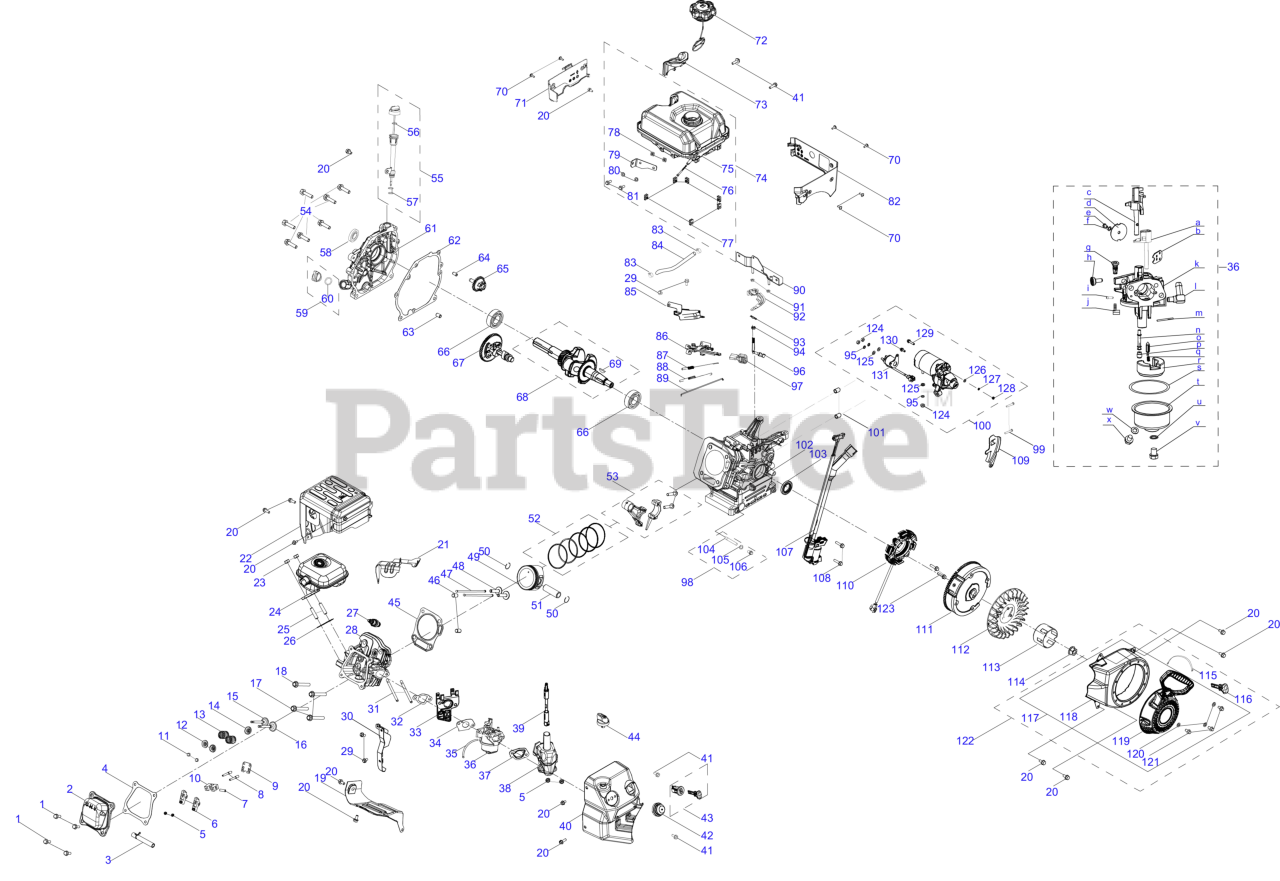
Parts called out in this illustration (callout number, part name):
1	BOLT M6 x 16
2	VALVE COVER
3	BREATHER HOSE
4	VALVE COVER GASKET
5	HEX NUT
6	ROCKER ARM ASSEMBLY
7	ROCKER ARM SHAFT
8	PIVOT BOLT
9	PUSH ROD GUIDE
10	ROCKER ARM PIVOT BLOCK
11	EXHAUST VALVE ADJUSTER
12	EXHAUST VALVE SPRING RETAINER
13	VALVE SPRING
14	INTAKE VALVE SEAL
15	EXHAUST VALVE
16	INTAKE VALVE
17	SCREW M10-1.25 x 65 x GR10.9
18	BOLT M10-1.25 x 70
19	AIR SHIELD
20	BOLT M6-1 x 12 GR8.8
21	SHROUD
22	MUFFLER GUARD
24	MUFFLER
26	MUFFLER GASKET
27	SPARK PLUG (F6RTC/RN11YC/BPR6ES)
28	CYLINDER HEAD
29	BOLT M6-1 x 12 GR8.8
30	SNOW GUARD
31	STUD M6 x 90
32	CARBURETOR INSULATOR GASKET
33	INSULATOR
34	CARBURETOR GASKET
35	PRIMER HOSE
36	CARBURETOR ASSEMBLY 175SC
37	CARBURETOR GASKET PLATE
38	HEATER BOX
39	CHOKE LEVER
40	CONTROL PANEL
41	BOLT M6-1 x 18 GR8.8
43	ENGINE KEY SWITCH ASSEMBLY
44	CHOKE LEVER
45	CYLINDER HEAD GASKET
46	PIN 12X16
47	PUSH ROD (SINGLE)
48	TAPPET
49	PISTON
50	PISTON PIN SNAP RING
51	PISTON PIN
52	PISTON RING SET
53	CONNECTING ROD
54	BOLT M8-1.25 x 32 GR5.8
55	DIPSTICK ASSEMBLY
57	OIL FILL TUBE O-RING
58	OIL SEAL
59	OIL PLUG
60	O-RING 15.8 x 2.5
61	CRANKCASE COVER
62	CRANKCASE GASKET
63	DOWEL PIN 9 X 14
64	DOWEL PIN 9 X 14
65	GOVERNOR GEAR
66	BALL BEARING
67	CAMSHAFT
68	CRANKSHAFT ASSEMBLY
69	WOODRUFF KEY
70	BOLT: M5 x 14
71	FUEL TANK SHROUD (RH)
72	FUEL CAP
73	DECORATIVE COVER
74	FUEL TANK
75	Not Serviceable/ Order Complete Assembly
76	FUEL FILTER
77	FUEL TANK MOUNT THREADED TAB
78	NUT M6
79	FUEL TANK MOUNT TAB
80	WASHER 6.5 x 1.5 x 12
81	BOLT M6 x 20
82	DECORATIVE SHEET (LH)
83	CARBURETOR HOSE CLAMP
84	FUEL HOSE 6.3 x 12.5 x 162
85	GOVERNOR SHIELD
86	GOVERNOR GEAR BRACKET ASSEMBLY
87	GOVERNOR SPRING
88	THROTTLE SPRING
89	THROTTLE LINKAGE
90	FUEL TANK BRACKET
91	HEX NUT
92	GOVERNOR LEVER
93	COTTER PIN
94	GOVERNOR SEAL
95	WASHER M6
96	GOVERNOR SHAFT
97	THROTTLE LEVER KNOB
99	BOLT M6-1 x 32 GR8.8
100	ELECTRIC STARTER
101	DOWEL PIN
102	CRANKCASE
103	OIL SEAL
104	OIL DRAIN PIPE
105	WASHER
106	OIL DRAIN PLUG
107	IGNITION MODULE
108	BOLT M6-1 x 25 GR8.8
109	LOWER HOUSING
110	CHARGING COIL
111	FLYWHEEL
112	COOLING FAN
113	STARTER CUP
114	FLYWHEEL NUT
115	CABLE TIE - 3 x 150
116	IGNITION KEY
117	RECOIL STARTER
118	BLOWER HOUSING
119	RECOIL STARTER ASSEMBLY
120	FLAT WASHER
121	BOLT M6 x 10
122	Not Serviceable/ Components Only
123	BOLT-M6-1 x 28 GR8.8
124	NUT M6
125	FLAT WASHER
126	FLAT WASHER 5.2x10.0x1.0
127	WASHER
128	NUT M5
129	BOLT M5x22
130	BOLT M5x12
131	STARTER SOLENOID
